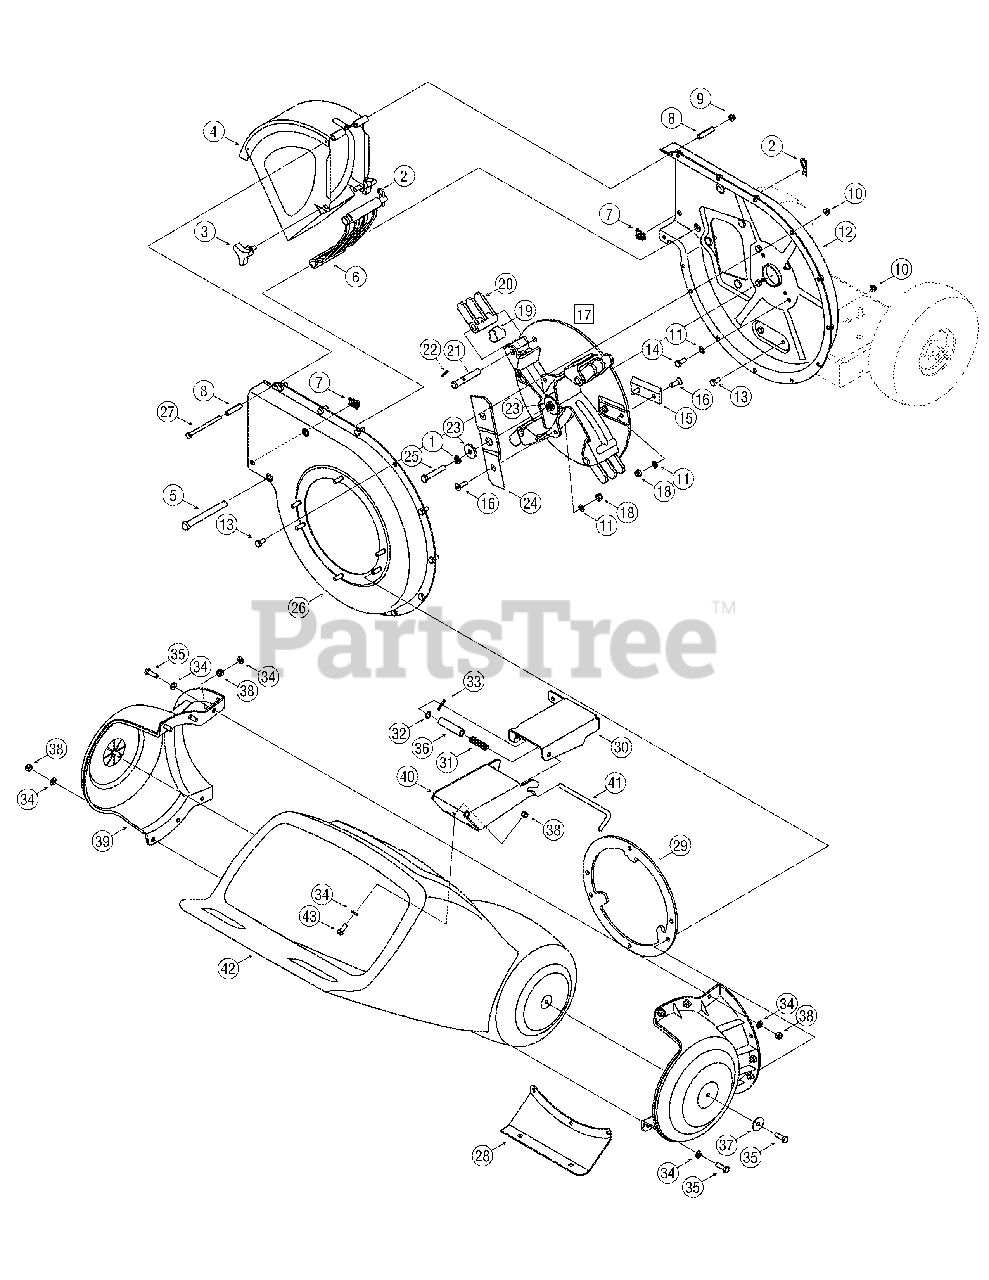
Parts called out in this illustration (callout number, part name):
1	Lock Washer, 3/8
2	Cotter Pin
3	Wing Knob 5/16-18
5	Clevis Pin
7	U-Nut 5/16-18
8	Spacer
9	Hex Lock Nut, 1/4-20
10	Hex Lock Nut 5/16-18
11	Lock Washer 5/16
13	Hex Cap Screw 5/16-18 x.625
14	Hex Cap Screw 5/16-24 x.75
15	Chipper Blade
16	Hex Cap Screw 5/16-24 x 1.0
17	Impeller Assembly
18	Hex Lock Nut 5/16-24
19	Retainer Pin Clip
20	Flail Blade
21	Clevis Pin
23	Flat Washer 3/8 x 1.25
24	Shredder Blade
25	Hex Cap Screw 3/8-24 x 2.25
27	Hex Cap Screw 1/4-20 x 3.75
31	Compression Spring 1.75
32	Flat Washer
33	Cotter Pin
34	Flat Washer.330 ID x.630 OD
35	Hex Cap Screw 5/16-18 x 1.0
36	Spacer,.375 ID x 2.50 LG
37	Flat Washer.320 ID x 1.25 OD
38	Hex Lock Nut 5/16-18
39	Hopper Collar
41	Lock Rod
42	Hopper Assembly
43	Hex Cap Screw 5/16-18 x.75
